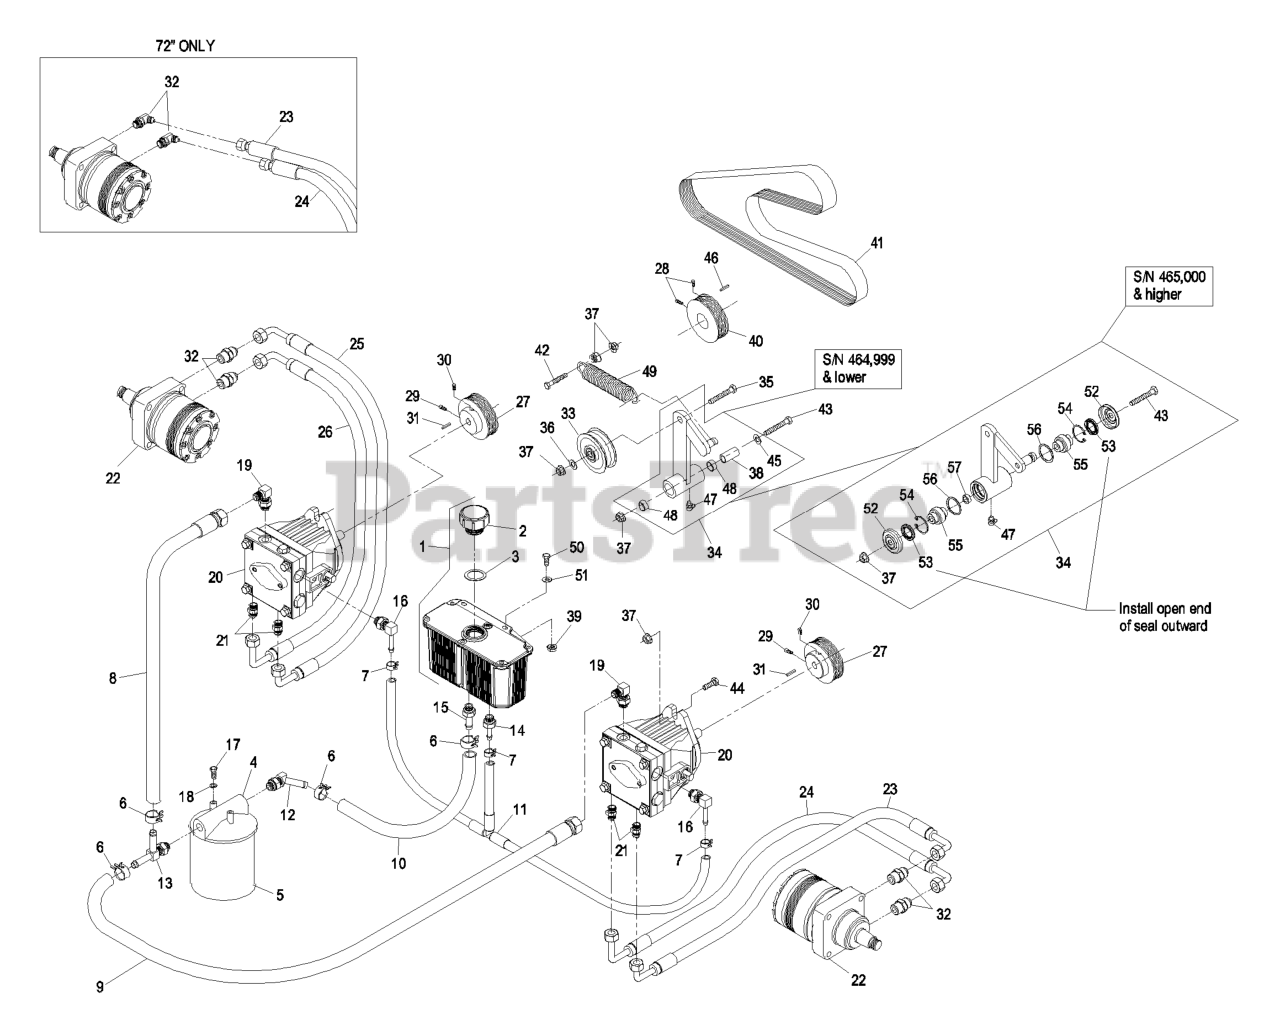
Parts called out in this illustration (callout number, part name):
1	HYD RESERVOIR ASM
2	Cap-Reservoir, HYD
3	GASKET-CAP
4	HEAD-FILTER
6	CLAMP-HOSE
7	CLAMP-HOSE
8	HYD HOSE ASM
9	HYD HOSE ASM
10	HOSE-HYD
11	HYD HOSE ASM
12	FITTING-BARBED, 45 DEG
13	ADAPTER-RUN, TEE
14	ADAPTER-STRAIGHT
15	ADAPTER-STRAIGHT
16	ELBOW-90 DEG
17	SCREW-HH
18	WASHER-LOCK
19	FITTING-ELBOW, 90 DEG
20	PUMP-HYD
21	FITTING-STRAIGHT
22	MOTOR-WHEEL
23	HYD HOSE ASM
24	HYD HOSE ASM
25	HYD HOSE ASM
26	HYD HOSE ASM
28	SCREW-SET
29	SCREW-SET
30	SCREW-SET
32	FITTING-STRAIGHT
33	SHEAVE-IDLER
34	KIT,PUMP IDLER LZ
35	SCREW-HH
36	WASHER-FLAT
37	NUT-HHF, WHIZ
38	BUSHING-PIVOT, IDLER
41	BELT,POLY-V 5K
42	SCREW-HH
43	SCREW-HH
44	SCREW-HH
45	WASHER-FLAT
46	KEY-SQUARE
47	FITTING-GREASE, 90 DEG
48	SLEEVE-BEARING
50	SCREW-HH
51	WASHER-FLAT
52	GUARD-TOP
53	SEAL-LIP, SINGLE
54	RING-SNAP
55	BEARING-SPHERICAL
56	O-RING
57	SPACER
